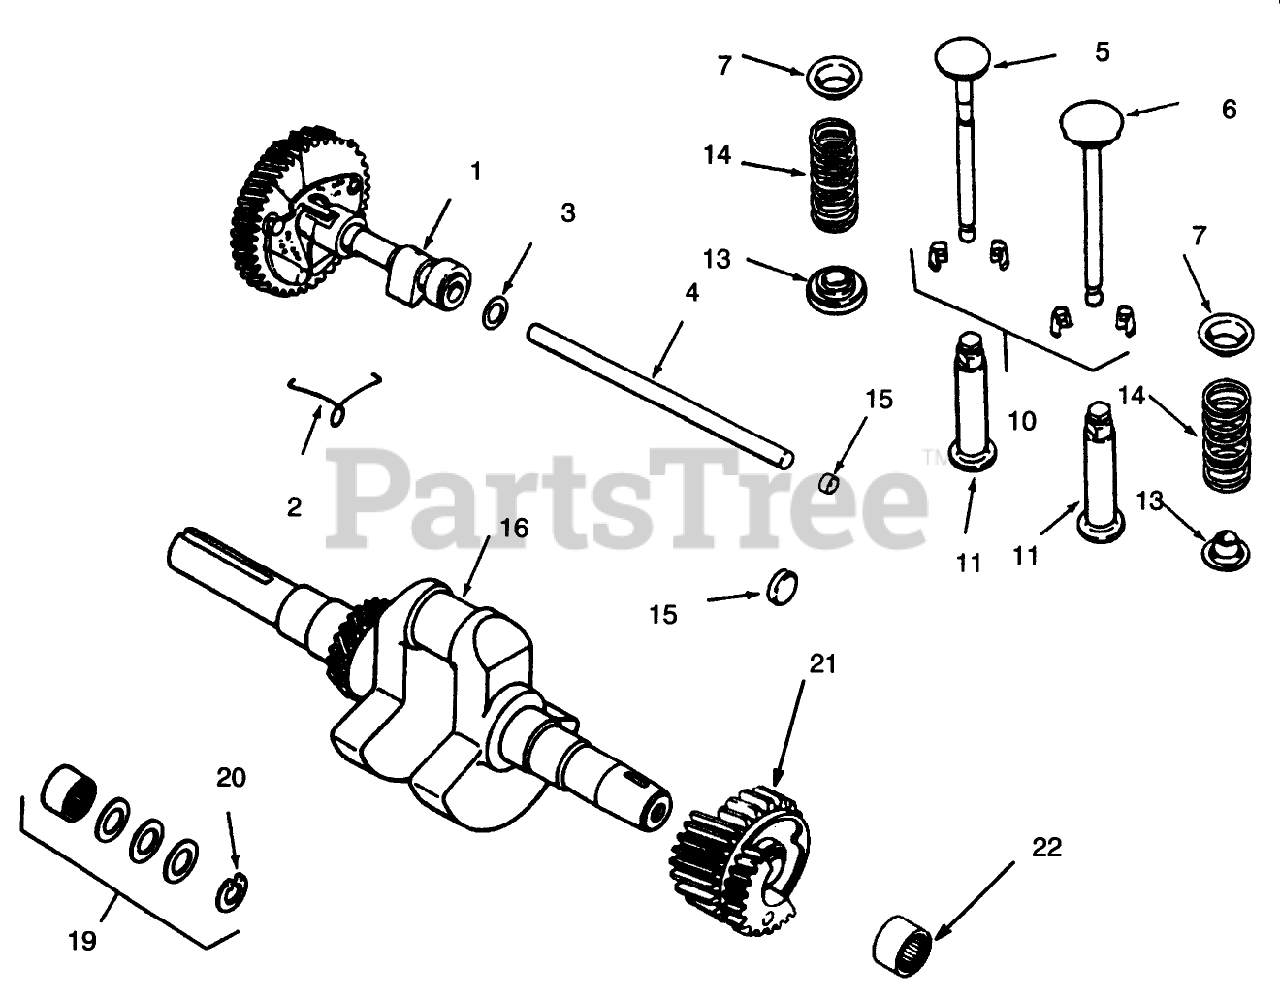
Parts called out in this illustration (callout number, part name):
1	KOHLER 47-010-11
2	KOHLER 47-089-01
3	KOHLER 275066
4	KOHLER 47-380-09
5	KOHLER 237672
6	KOHLER 235582
7	KOHLER 235011
10	KOHLER 41-755-10
11	KOHLER D-235327
13	KOHLER 52-413-01
14	KOHLER 235168
15	KOHLER X-702-3
16	KOHLER 45-142-21
19	KOHLER 47-755-01
20	KOHLER X-269-34
21	KOHLER 45-043-03
22	KOHLER 47-030-01
